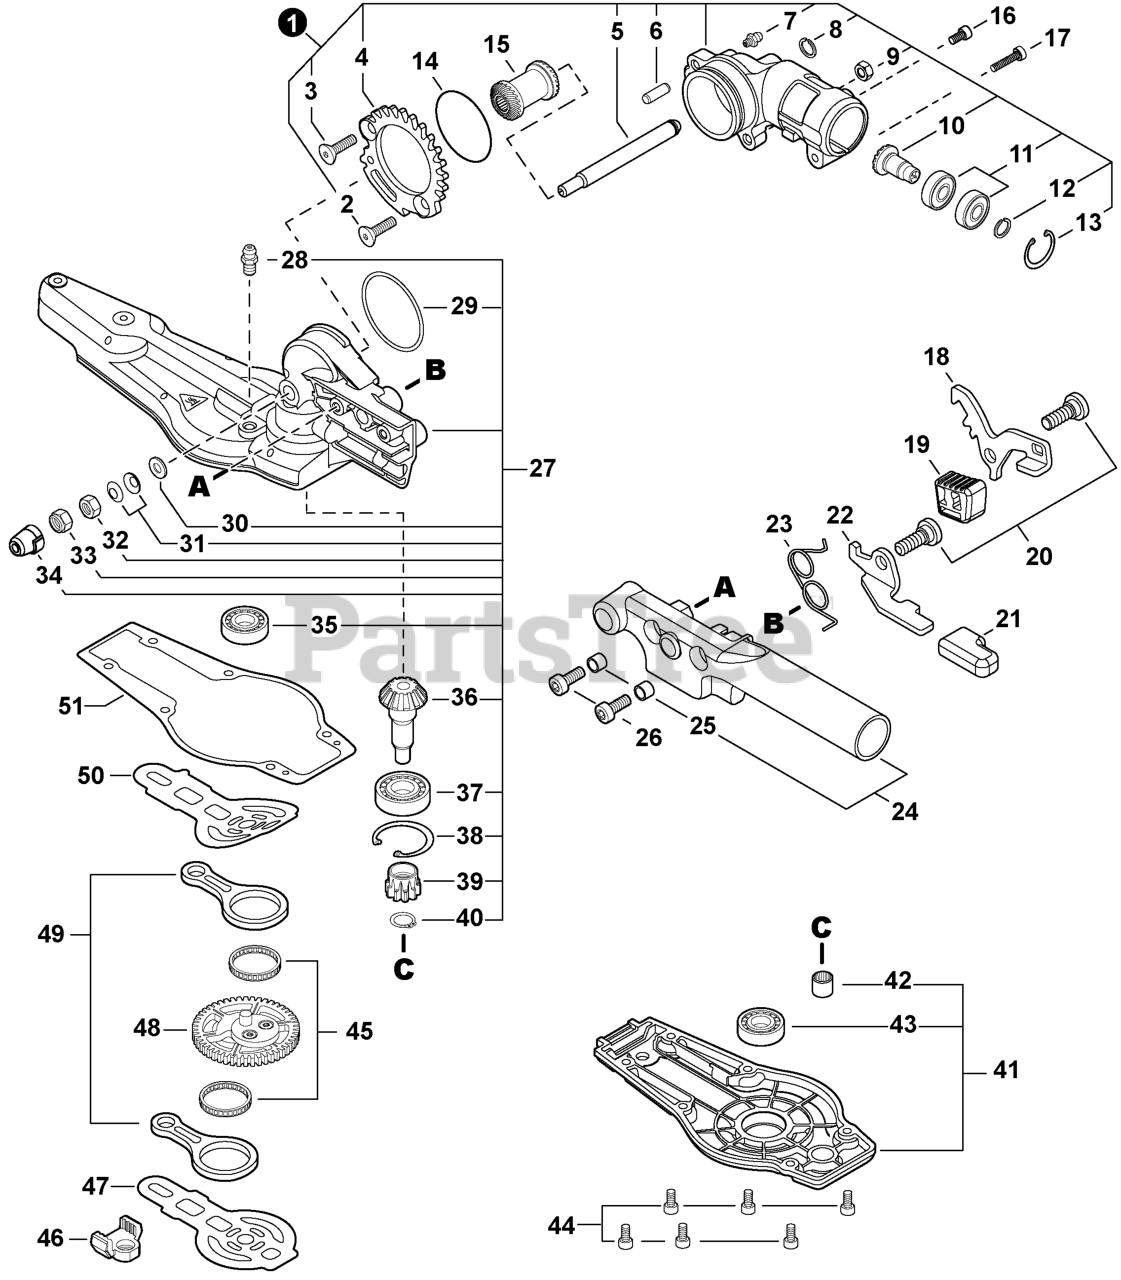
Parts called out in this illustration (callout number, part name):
1	GEAR CASE ASSY
2	BOLT 5x12
3	BOLT - 5x18
4	RING, LOCKING
5	SHAFT, GEAR
6	PIN 5 L19.5
7	FITTING, GREASE
8	E-RING 8
9	NUT, LOCK M5
10	GEAR, BEVEL
11	BEARING, BALL 6901
12	RING, SNAP 12
13	RING, SNAP 24
14	O-RING 35
15	GEAR, BEVEL
16	BOLT, TORX 5x10
17	BOLT, TORX 5x25
18	LEVER, LOCK
20	BOLT M6
22	RELEASE, LOCK
23	SPRING, TORSION
24	LEVER, ADJUSTMENT
25	SPACER 6.2x7.8x6
26	BOLT, TORX 5x16
27	GEAR CASE ASSY
28	FITTING, GREASE
30	WASHER 6
33	NUT, LOCK 6
34	COVER, DUST
35	BEARING, BALL 608
36	SHAFT, PINION
37	BEARING, BALL 6001
38	RING, SNAP 28
39	GEAR, SPUR
40	RING, RETAINING 8
41	COVER ASSY, GEAR CASE
42	BEARING, NEEDLE
43	BEARING, BALL 608
44	BOLT, TORX 4x12
45	BEARING, NEEDLE 30
47	PLATE, WEAR
48	GEAR, SPUR
49	ROD, CONNECTING
50	PLATE, WEAR
51	GASKET, GEAR CASE
